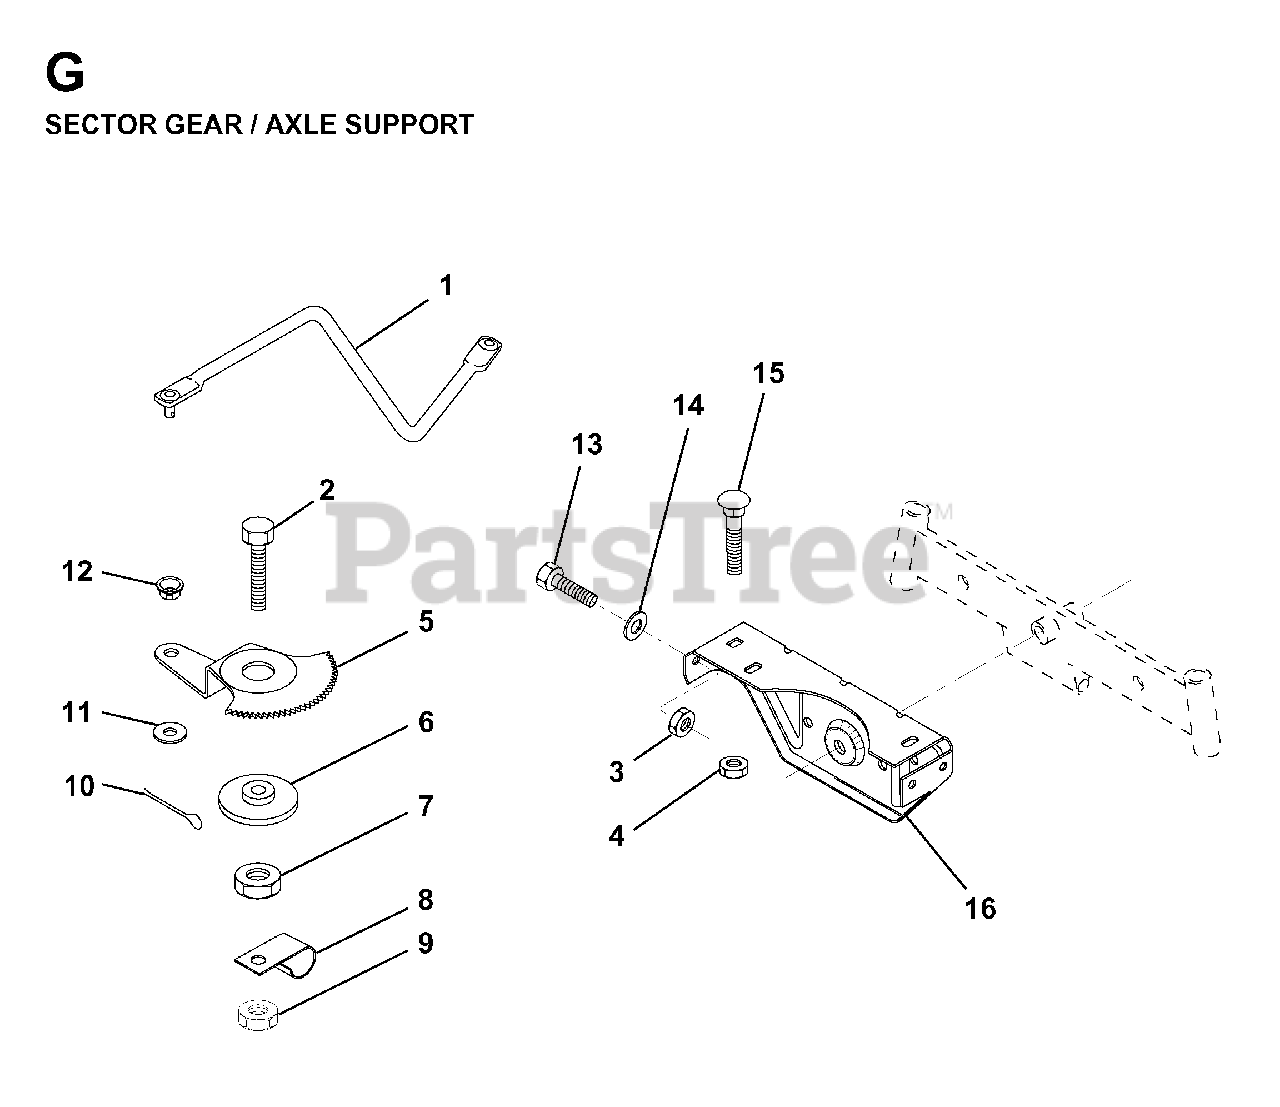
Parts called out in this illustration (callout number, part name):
1	LINK DRAG
3	LOCKNUT
4	LOCKNUT
5	GEAR SECTOR
7	NUT
8	CLIP INSULATOR
9	NUT LTV
10	COTTER PIN
12	BUSHING.DRAGLINK
13	BOLT
14	WASHER
16	SUPPORT/AXLE FRONT
